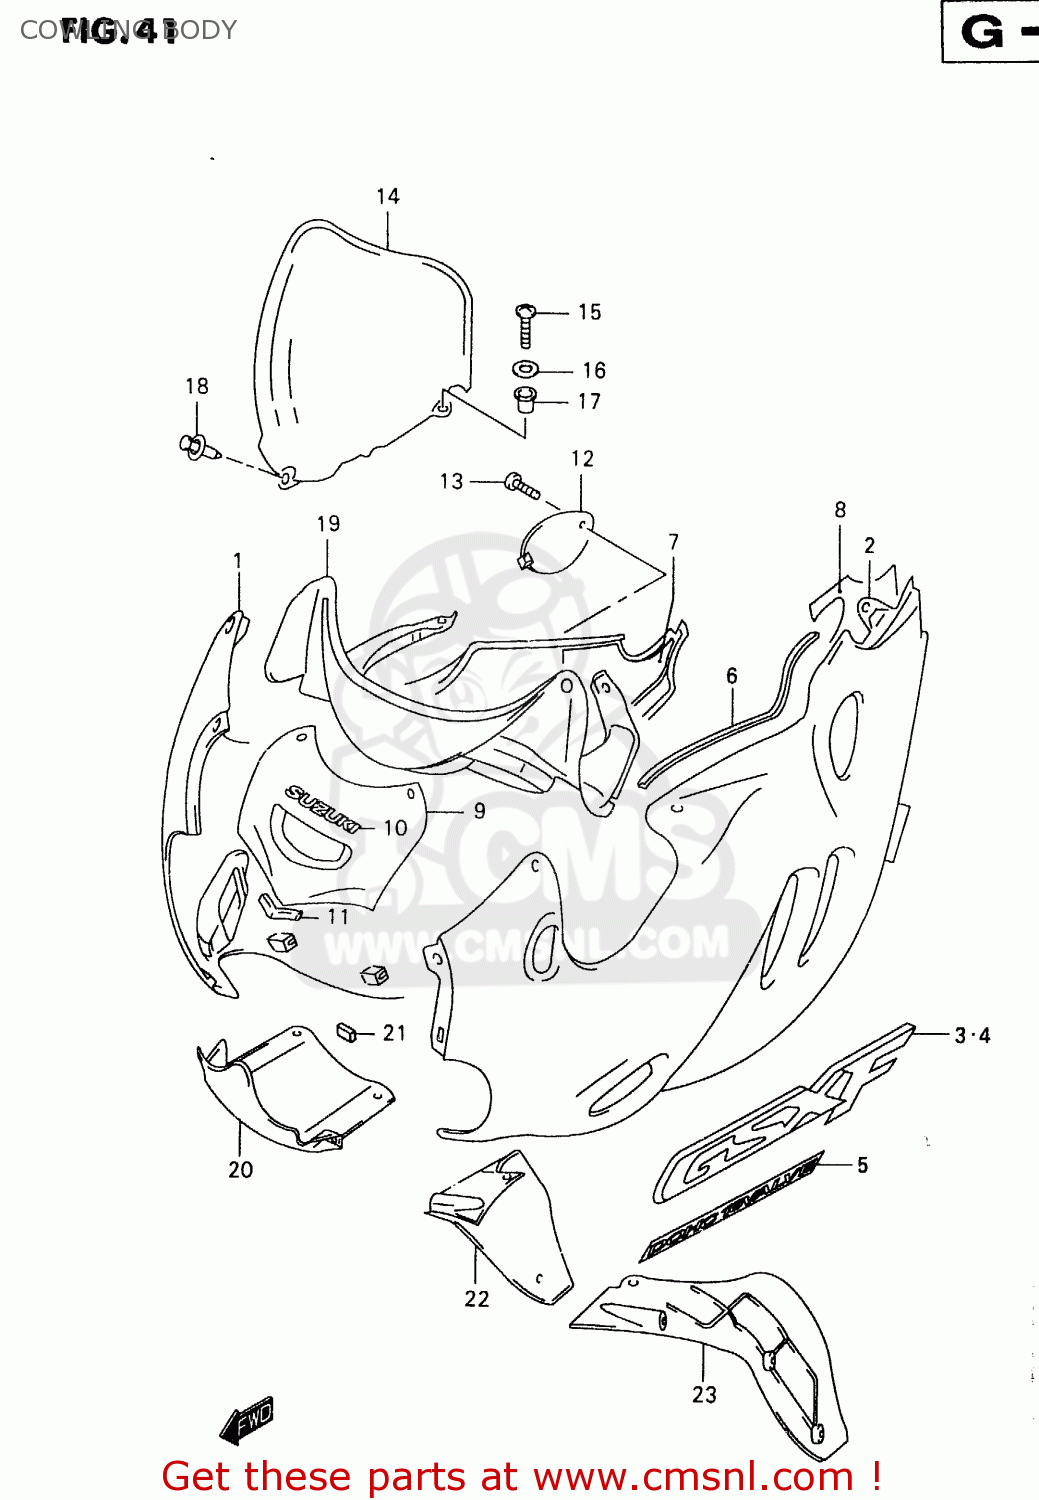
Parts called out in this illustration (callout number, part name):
1	COWLING ASSY,SIDE,R
2	COWLING,SIDE,L
3	EMBLEM,COWLING SIDE,GSXF,R
4	EMBLEM,COWLING SIDE,GSXF,L
5	EMBLEM,COWLING SIDE
6	MOLD,COWLING
7	SHIELD,COWLING COVER,R
8	SHIELD,COWLING COVER,L
9	PANEL,COWLING CTR UPR
10	EMBLEM,SUZUKI(SILVER)
11	CUSHION,CTR PANEL UPR
12	LID,OIL
13	SCREW(6X16)
14	WINDSCREEN
15	SCREW(5X14)
16	WASHER
17	NUT
18	CLIP(BLACK)
19	PANEL,METER
20	PANEL,COWLING CTR LWR
21	CUSHION,CENTER PANEL,LOWER
22	PANEL,COWLING INNER,R
23	PANEL,COWLING INNER,L
